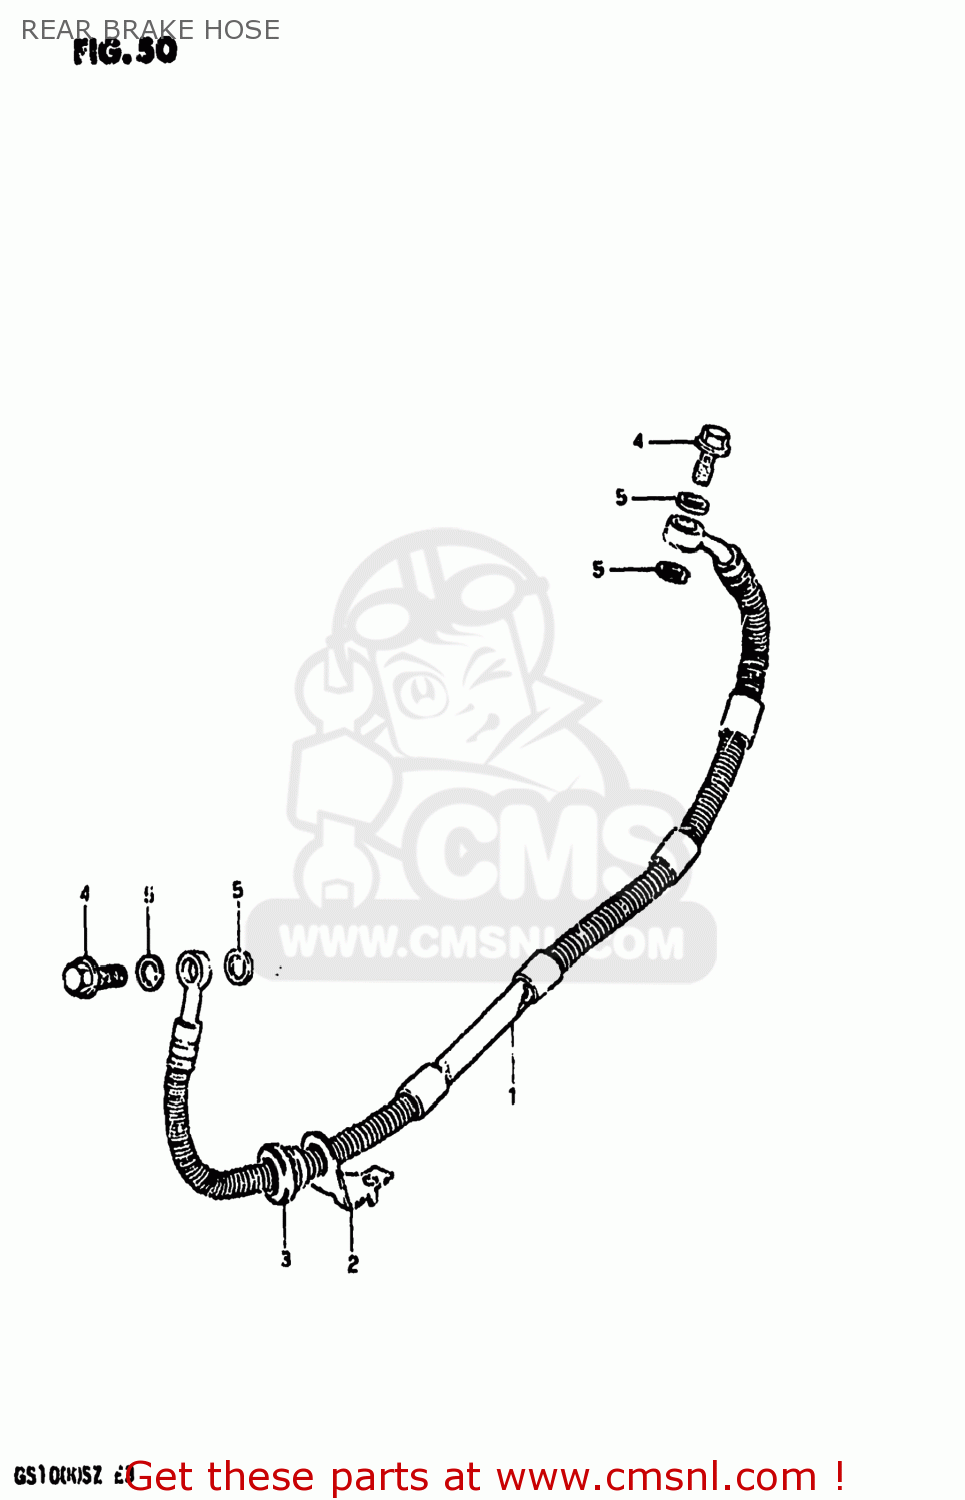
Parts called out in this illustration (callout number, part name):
1	HOSE,REAR BRAKE
2	GUIDE,BRAKE HOSE
3	GROMMET,BRAKE HOSE GUIDE
4	BOLT,UNION
5	WASHER
